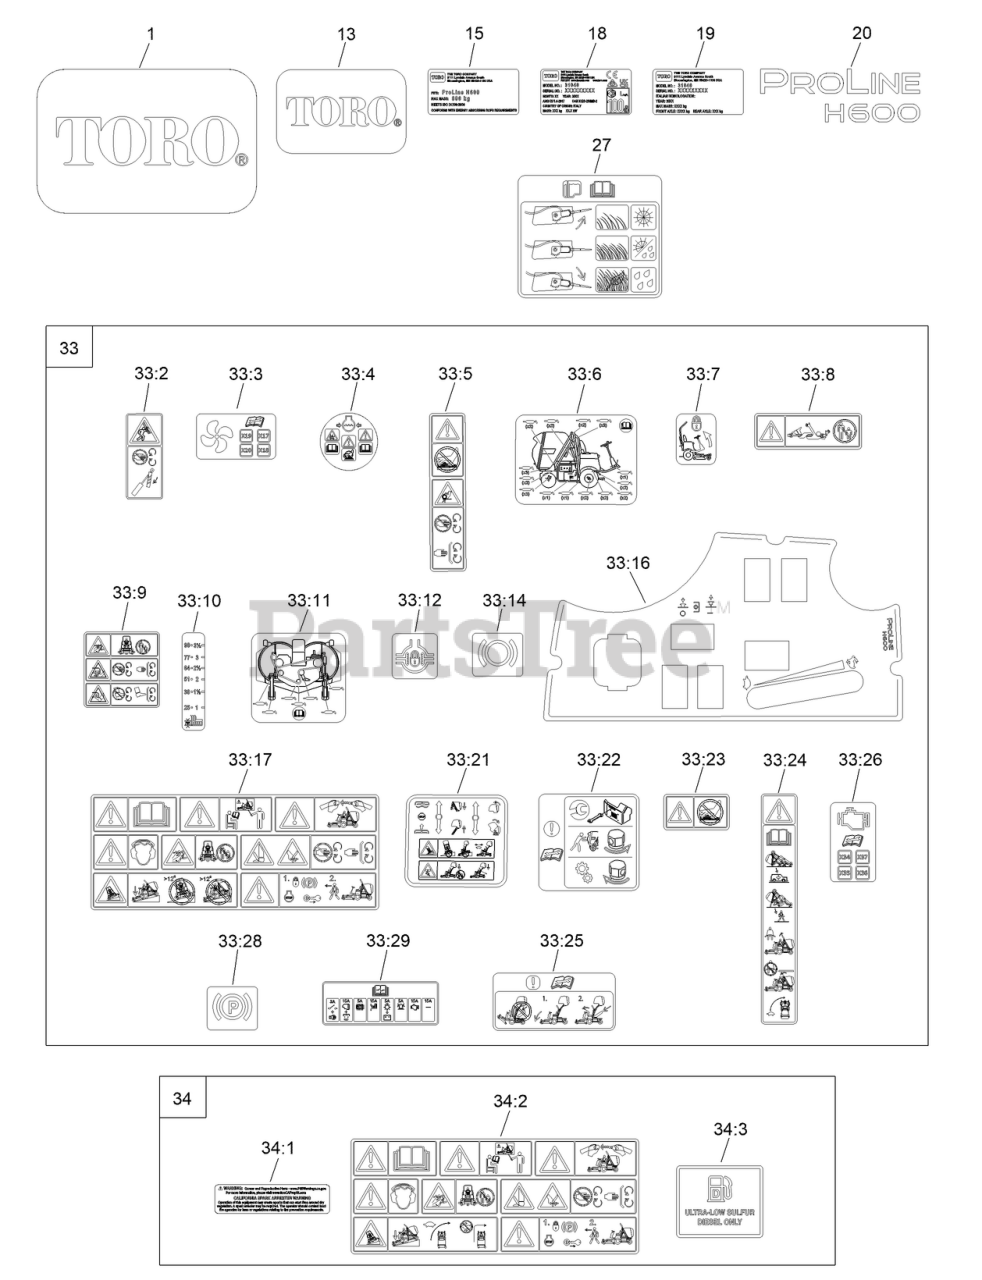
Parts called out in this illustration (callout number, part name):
13	DECAL-LOGO, TORO
15	DECAL-ROPS COMPLIANCE
18	DECAL-MODEL/SERIAL
19	DECAL-HOMOLOGATION
20	DECAL-PROLINE H600
27	DECAL-HOPPER SENSOR
33	Proline H600 DECAL SET
33:2	DECAL-WARNING ARM
33:3	DECAL-RELAY FAN
33:4	DECAL-DANGER
33:5	DECAL-WARNING ENGINE
33:6	DECAL-SERVICE
33:7	DECAL-FOOTPLATE TILT
33:8	DECAL-CARDAN JOINT
33:9	DECAL-WARNING DECK
33:10	DECAL-HOC
33:11	DECAL-SERVICE
33:12	DECAL-DIFFERENTIAL LOCK
33:14	DECAL-BRAKE
33:16	DECAL-CONTROL PANEL
33:17	DECAL-WARNING
33:21	DECAL-CONTROLS SAFETY
33:22	DECAL-HYDROSTATIC PUMP BYPASS
33:23	DECAL-HOT SURFACE
33:24	DECAL-ROPS WARNING
33:25	DECAL-ATTENTION, DECK SERVICE
33:26	DECAL-ENGINE RELAY
33:28	DECAL-PARKING BRAKE
33:29	DECAL-FUSE
34	ANSI DECAL KIT
34:1	DECAL-ARRESTOR, SPARK
34:2	DECAL-WARNING
34:3	DECAL-DIESEL, ULTRA-LOW
